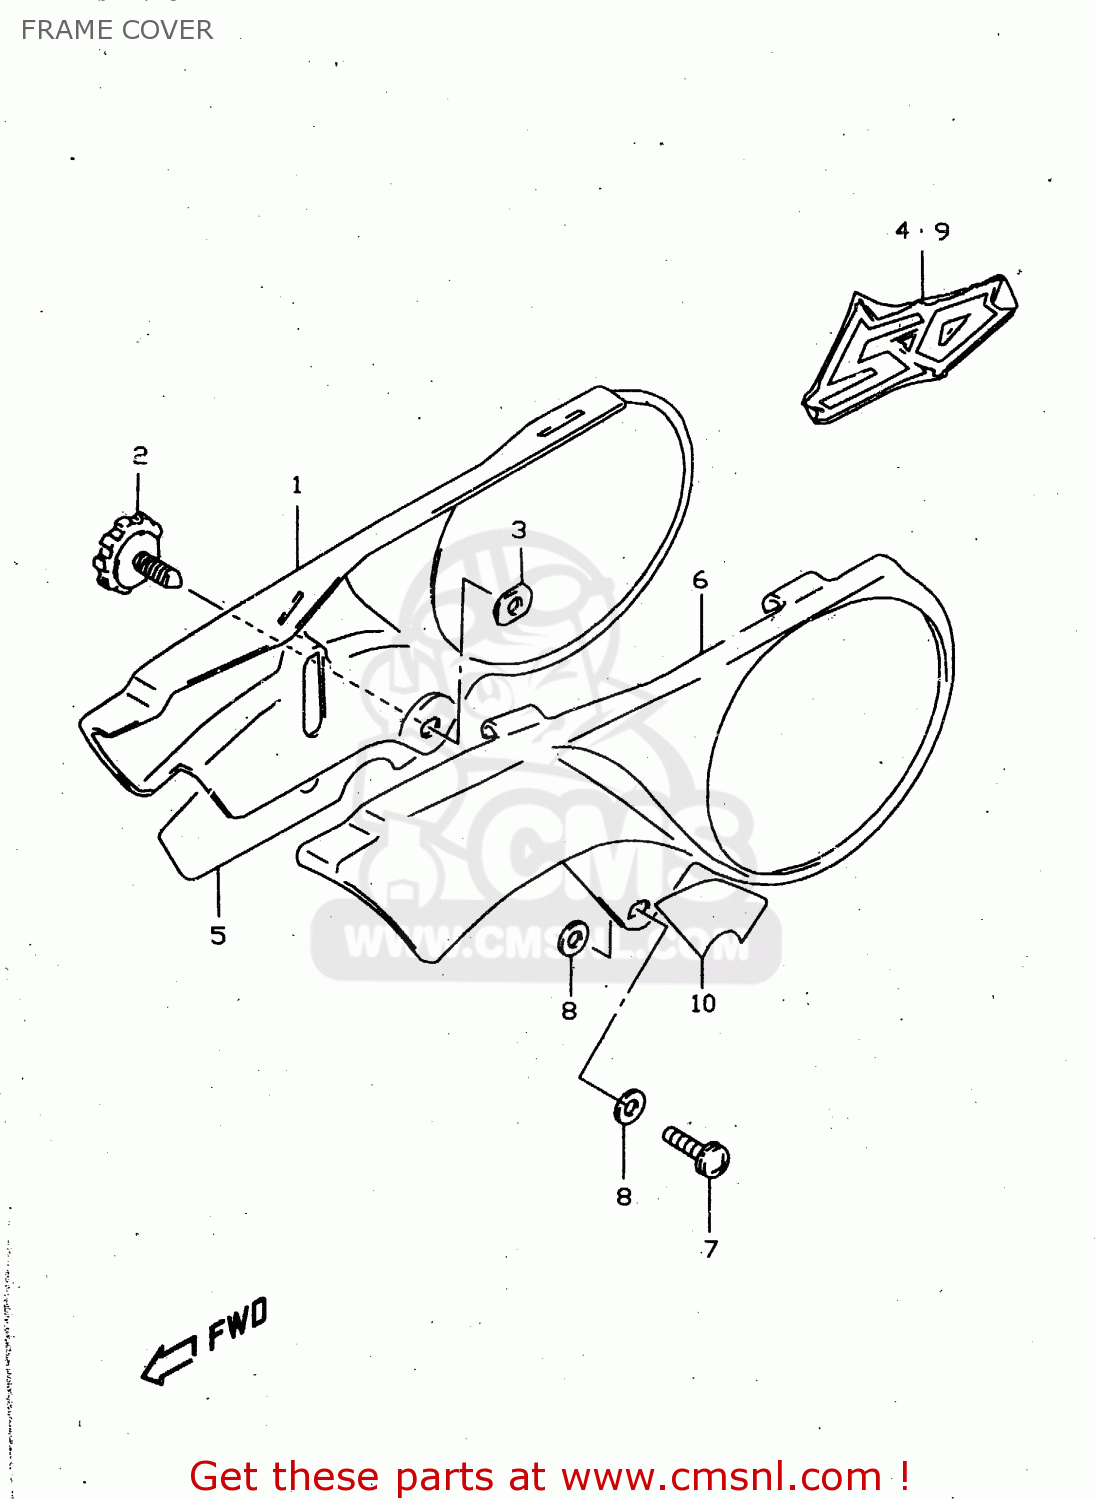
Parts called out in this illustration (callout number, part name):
1	COVER,FRAME,R(WHITE)
2	KNOB,FRAME COVER,R
3	NUT
4	EMBLEM,FRAME COVER
5	EMBLEM,FRAME COVER,R LWR
6	COVER,FRAME,L(WHITE)
7	SCREW
8	WASHER(6.5X18X1.6)
9	EMBLEM,FRAME COVER
10	EMBLEM,FRAME COVER,L LWR
